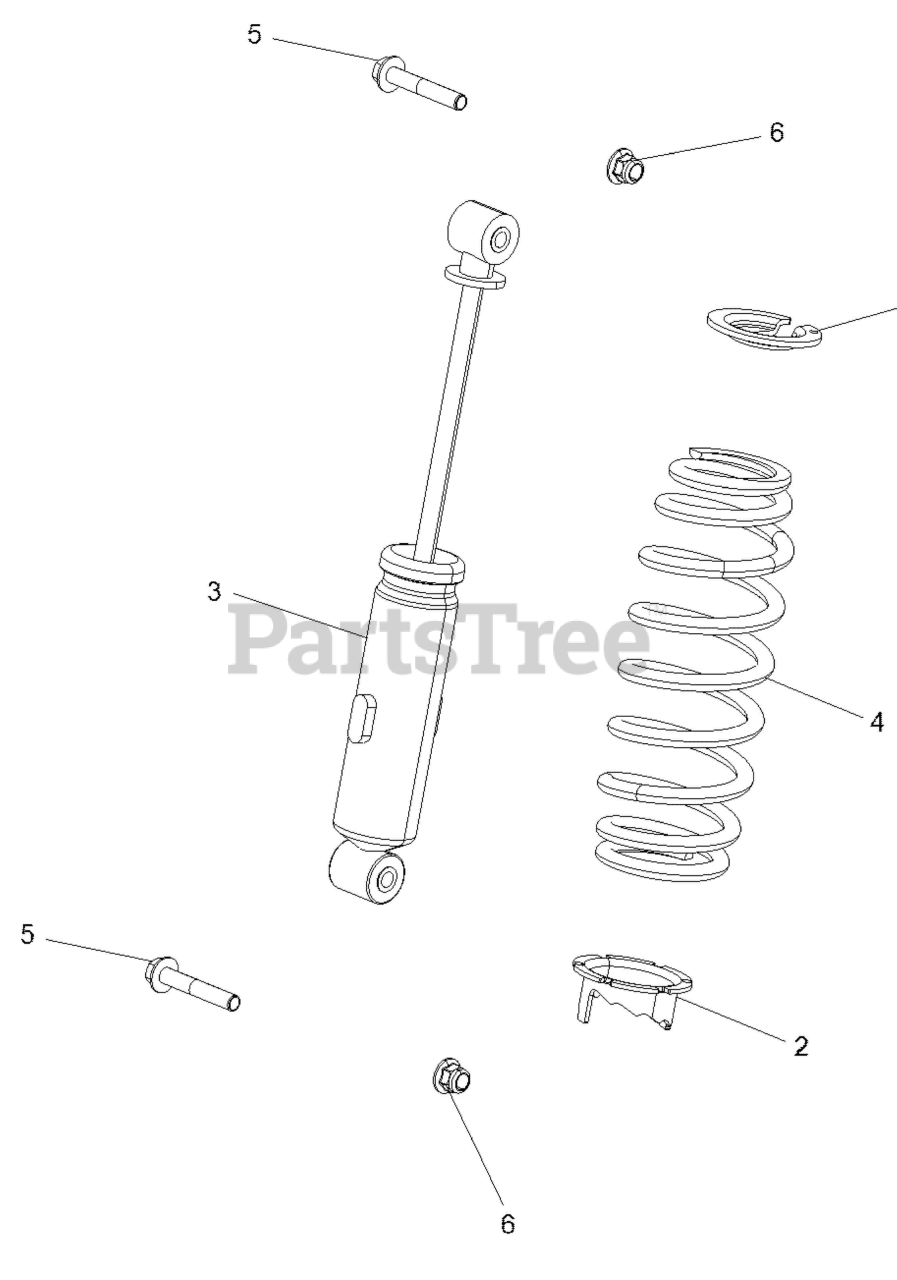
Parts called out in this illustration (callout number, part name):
1	RETAINER-SPRING,STEEL
2	CAM-ADJUSTING,SPRING,STEEL
3	SHOCK-FRONT
4	SPRING, FRONT, MATTE BLACK
5	SCR-HXFL-M10X1.5X65 10.9 RIE
6	NUT-M10X1.5 HFN NYLOC ZOD
